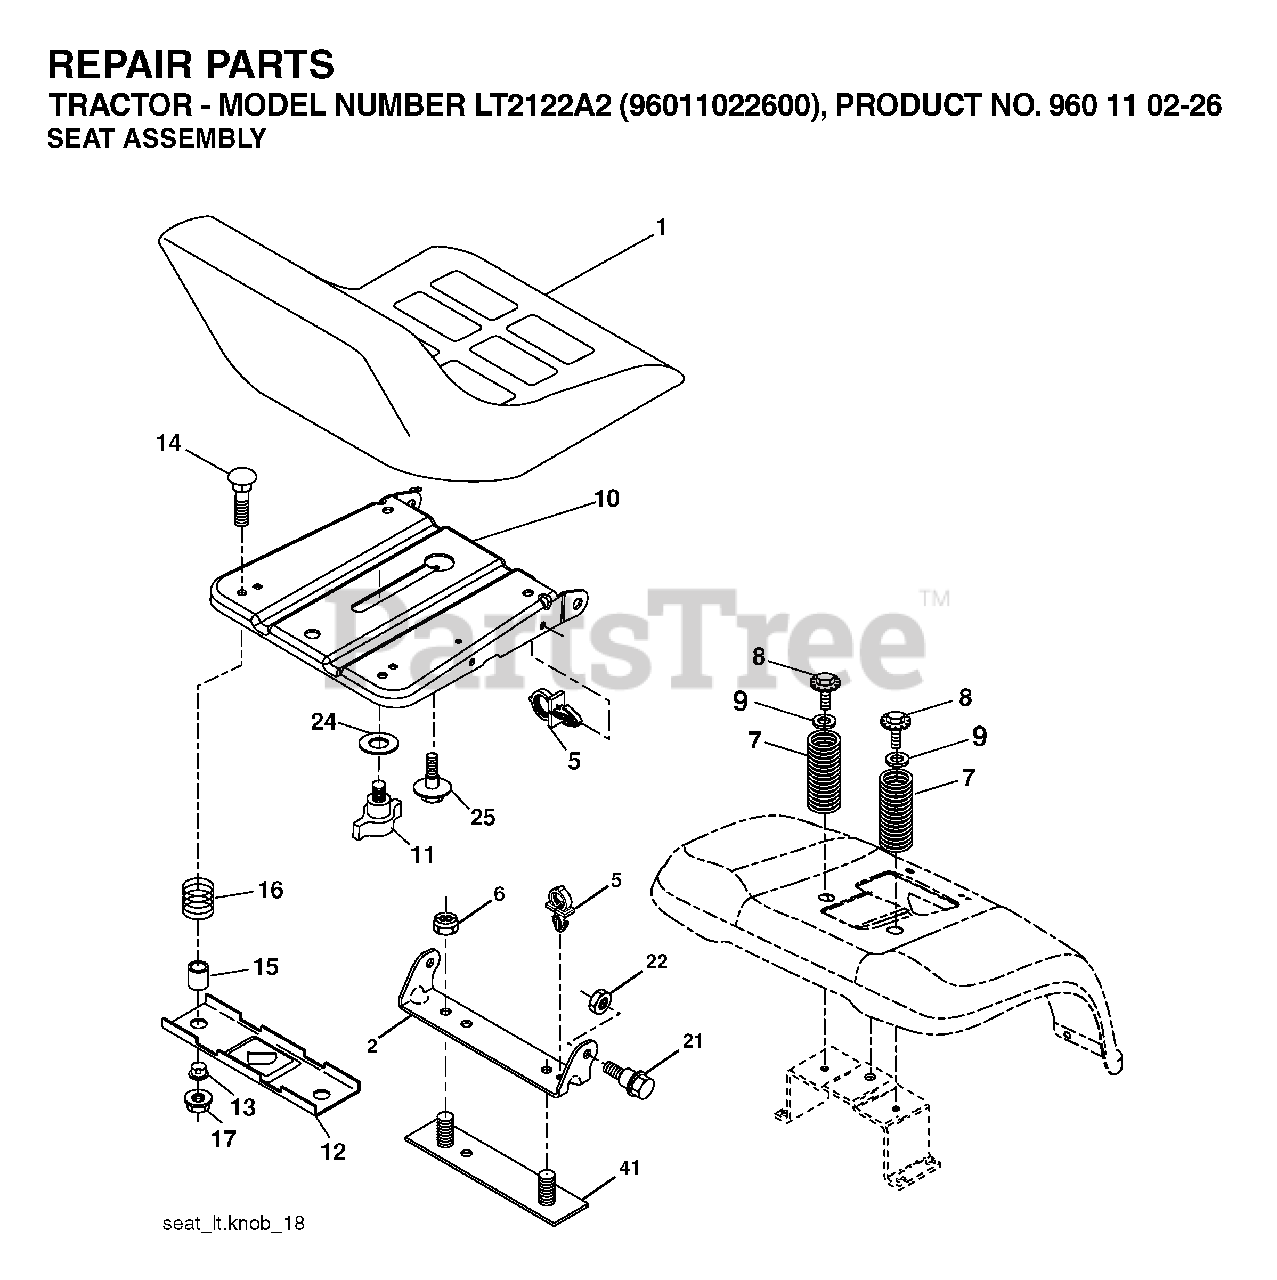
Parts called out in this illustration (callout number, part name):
1	SEAT.XG150.BLK.KB/SLD.NO-LOGO
2	SEAT PIVOT BRKT
5	PUSH CLIP
6	NUT
7	SPRING COMPRESSION
8	SCREW 3/8-16X1
9	WASHER
10	PAN.ASM.SEAT.1SLOT
11	KNOB.SEAT.ADJ.WINGNUT
12	BRKT.MNTNG.SWITCH.SEAT
14	BOLT.ROUND.HEAD.SQUARE.NECK
15	SPACER SPLIT
16	SPRING COMPRESSED
17	NUT T
21	BOLT.SHOULDER.5/16-18
22	NUT.71038.31-18.HEX.NYLOCK
25	BOLT,SHOULD
